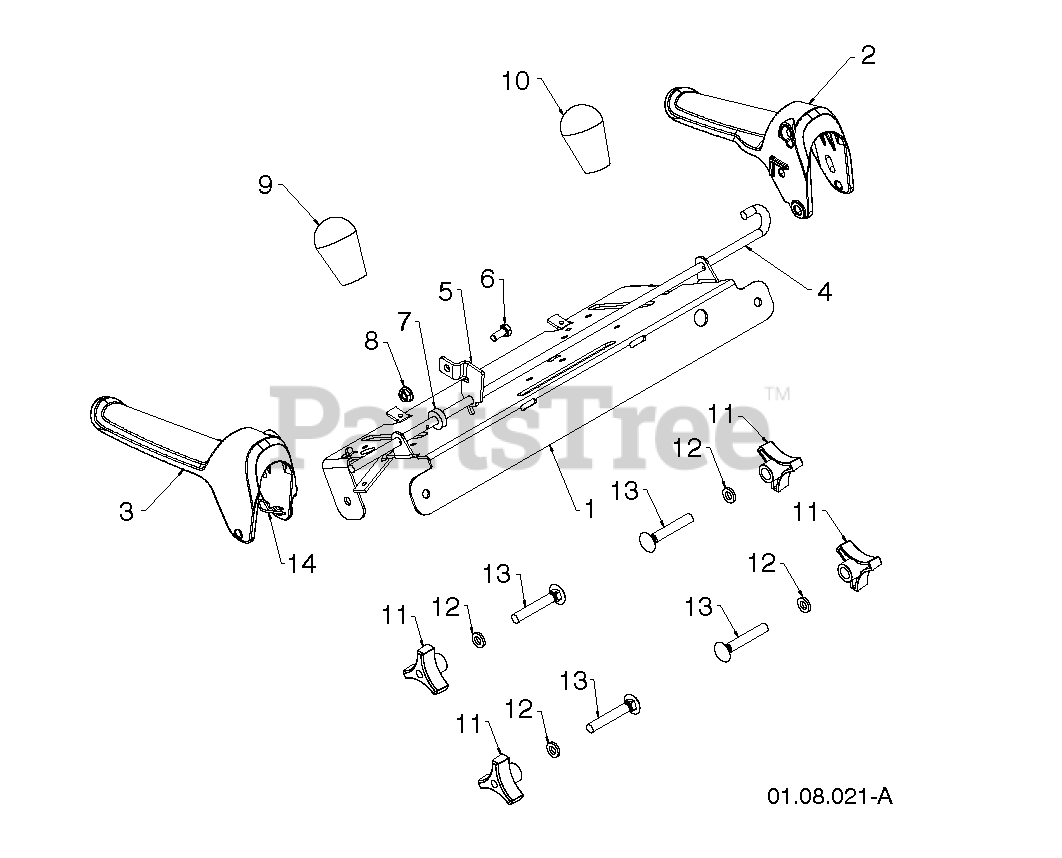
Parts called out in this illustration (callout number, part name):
1	PANEL.CONTROL.SNOW.BLACK
2	LEVER.CONTROL.LH.PL.BLACK
3	LEVER.CONTROL.RH.PL.BLACK
4	BAIL.CONTROL.INTERLOCK.SNOW
5	ARM.IMPELLER.ROD.
6	BOLT
7	SPACER.CONTROL.LEVER
9	RED KNOB SHIFTER
10	KNOB LEVER, BLACK
11	KNOB.HANDLE.3/8.TRI-POINT.BLAC
13	BOLT 3/8-16 X 2-1/4
14	SPRING RETAINER
